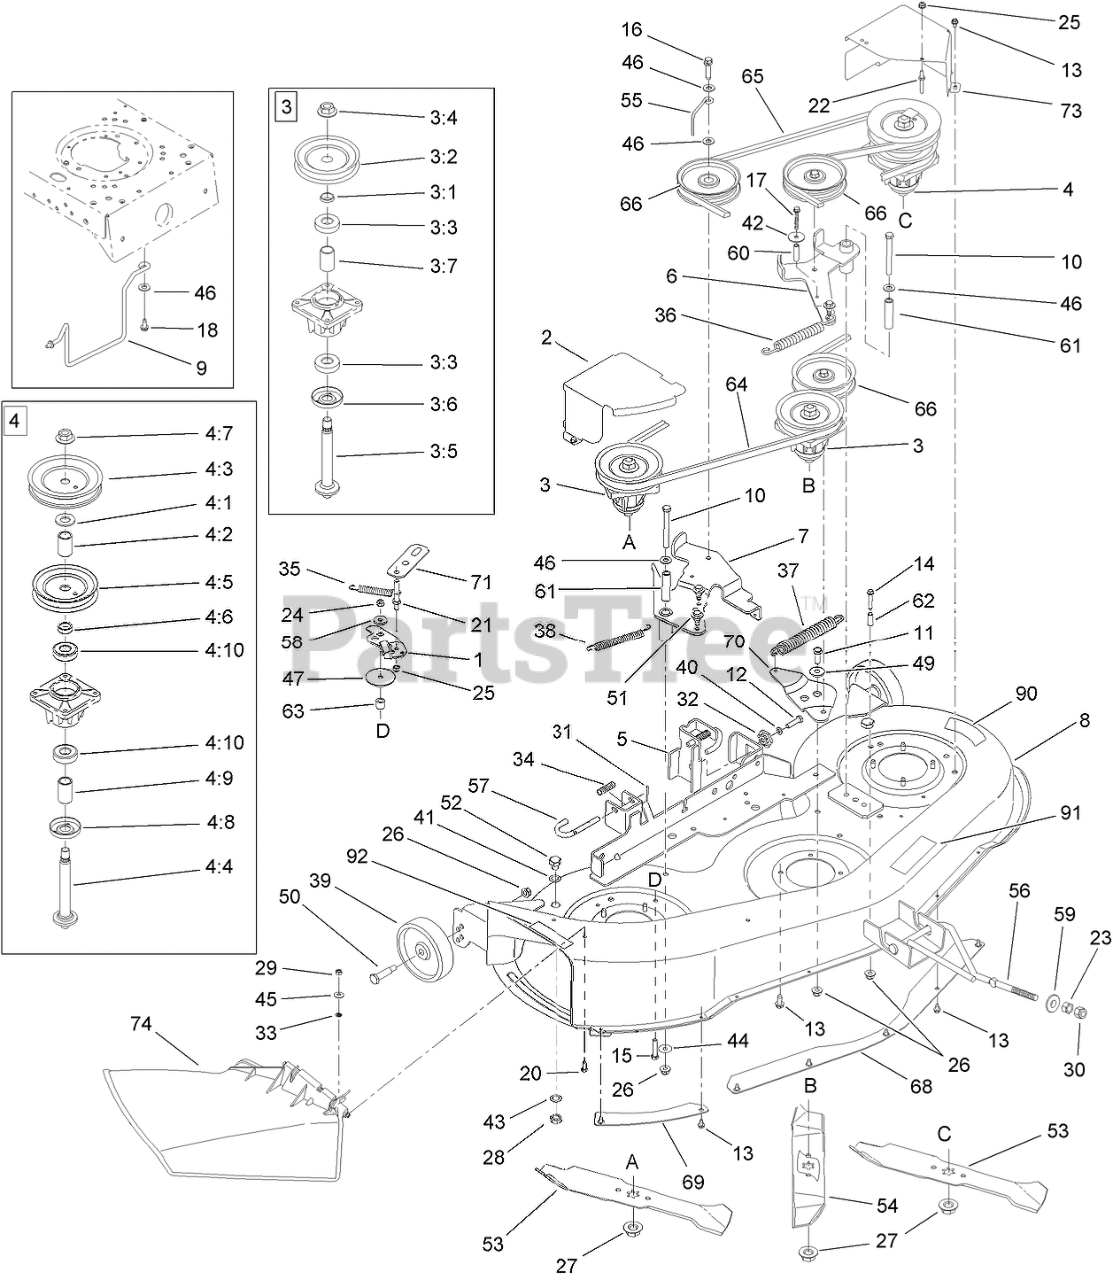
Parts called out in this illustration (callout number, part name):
1	DECK BRAKE BRACKET ASM
2	COVER-BELT, RH
3	SPINDLE ASM
3:1	SPACER
3:2	PULLEY-DECK
3:3	BEARING-BALL
3:4	NUT-LOCK, FLANGE
3:5	SHAFT-SPINDLE
3:6	BEARING-SHOULDER
3:7	SPACER
4	DOUBLE PULLEY SPINDLE ASM
4:1	WASHER-FLAT
4:2	SPACER
4:3	PULLEY-DECK
4:4	SHAFT-SPINDLE
4:5	PULLEY-DECK
4:6	SPACER
4:7	NUT-LOCK, FLANGE
4:8	BEARING-SHOULDER
4:9	SPACER
4:10	BEARING-BALL
5	LH HANGER BRACKET ASM
6	LH IDLER ARM ASM
7	BRACKET ASM
8	Deck ASM
9	GUIDE-BELT, ENGINE
11	SCREW-HH
12	SCREW-HH
13	SCREW-HWHTF
14	SCREW-HWH
15	SCREW-HH
16	SCREW-TAP
17	SCREW-HH
18	SCREW-HWH
20	SCREW-HH
21	PIVOT-BRAKE, PIN
22	PIN-GUARD, BELT
23	NUT-HEX
24	NUT-LOCK, FLANGE
25	NUT-LOCK, FLANGE
26	NUT-LOCK, FLANGE
27	NUT-LOCK, FLANGE
28	NUT-HEX
29	NUT-HEX
30	NUT-LOCK, HEX (NYLON)
31	PIN-COTTER
32	GEAR-ADJUSTMENT, DECK
33	RETAINER-BOLT
34	SPRING-COMPRESSION
35	SPRING-EXTENSION
36	SPRING-EXTENSION
37	SPRING-EXTENSION
38	SPRING-EXTENSION
39	WHEEL-DECK, REAR
40	WASHER-LOCK
41	WASHER-FLAT
42	WASHER-FLAT
43	WASHER-LOCK
44	WASHER-FLAT
45	WASHER-SPRING
46	WASHER-FLAT
47	WASHER-FLAT
49	SPACER-SHOULDER
50	BOLT-SHOULDER
51	BOLT-SHOULDER, TAP
53	BLADE-16.28 INCH
54	BLADE-14.88 INCH
55	ROD-KEEPER, BELT
56	ROD-DECK
57	PIN-HANDLE, DECK RELEASE
58	SPACER-SHOULDER
59	CUP-PIVOT, LIFT
60	SPACER
61	SPACER
62	SPACER
63	SPACER
65	BELT-V
66	PULLEY-IDLER
68	SKIRT-CENTER, DECK
69	SKIRT-RH, DECK
70	BRACKET-IDLER
71	BRACKET BRAKE
73	COVER-BELT, LH
74	DISCHARGE CHUTE ASM
90	DECAL-DANGER
91	DECAL-ROUTING, BELT
92	DECAL-DANGER
